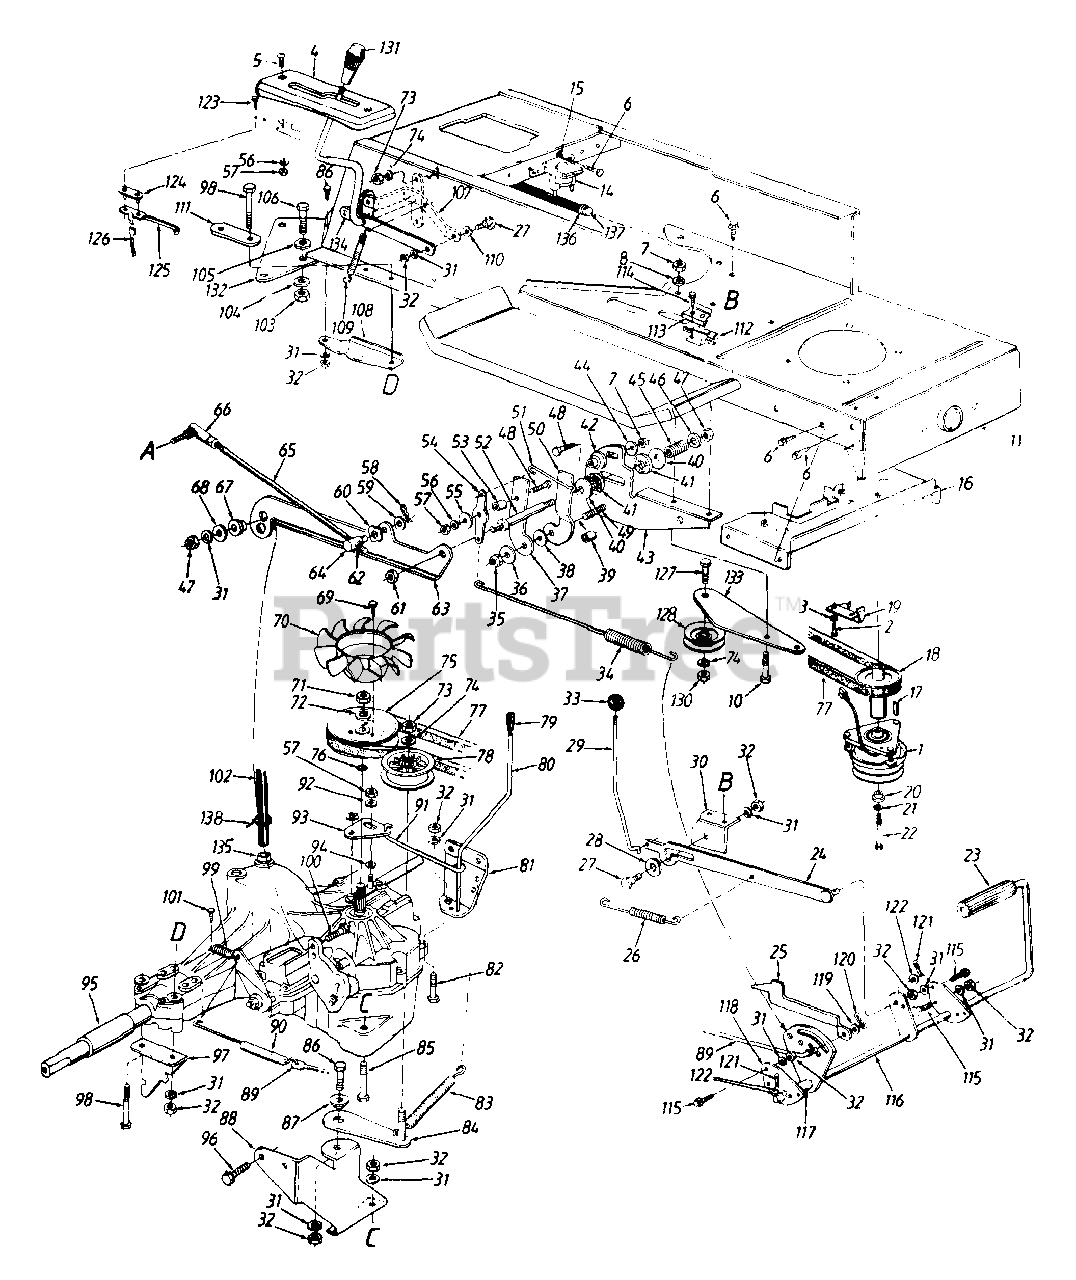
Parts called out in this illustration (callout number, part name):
1	Electric Clutch
2	Hex Bolt 5/16-18 x .75" Lg. (Gr. 5)
3	Bell-Wash. .345" I.D. x .88"
4	Index Bracket
5	Pan Hd. Mach. Scr. 1/4-20 x .75" Lg.
6	Hex Wash. Hd. TT-Tap Scr. 1/4-20 x .5" Lg.
7	Hex Nut 1/4-28 Thd.
8	L-Wash. 1/4" I.D.
10	Hex Bolt 1/4-28 x .75" Lg.
11	Lower Frame Ass'y.
14	Solenoid
15	Ext. L-Wash. 1/4" I.D.
16	Belt Guard Brkt. Ass'y.
17	Sq. Key 1/4" x 1.5" Lg.
18	Engine Pulley
21	L-Wash. 7/16" I.D.
22	Hex Bolt 7/16-20 x 3.25" Lg. (Gr. 5)
23	Foot Pad
26	Foot Pedal Return Spring
27	Shld. Bolt .437" Dia. x .268"
28	Fl-Wash. 7/16" I.D. x 1-3/8" O.D.
31	L-Wash. 5/16" I.D.
32	Hex Nut 5/16-18 Thd.
34	Neutral Return Spring
35	Hex Nut 5/16-24 Thd.
36	Fl-Wash. .344" I.D. x 1" O.D.
37	Scissor-Flat
38	Fl-Wash. .33" I.D. x 1.25" O.D.
40	Bell-Wash. .4" I.D. x 1.13" O.D.
41	Friction Washer
42	Centering Gauge Spacer
43	Neutral Return Mtg. Brkt.
44	Bell-Wash. .265" I.D. x .75" O.D.
45	Comp. Spring 1.19" Lg.
46	Fl-Wash. .312" I.D. x .75" O.D.
47	Hex Nut 5/16-24 Thd.
48	Hex Bolt 1/4-28 x 1" Lg. (Gr. 5)
49	Rib Neck Bolt 5/16-24 x .84" Lg.
50	Scissor-Offset
51	Neutral Return Rod
52	Friction Disc Stud
53	Shld. Spacer
54	Neutral Return Lever
55	Fl-Wash. .265" I.D. x 1" O.D.
56	L-Wash. 1/4" I.D.
57	Hex Nut 1/4-20 Thd.
58	Hairpin Clip
59	Fl-Wash. .375" I.D. x .87" O.D.
60	Spring Wash. .39" I.D.
61	Hex L-Nut 3/8-24 Thd.
62	Hex Jam Nut 3/8-24 Thd.
63	Neutral Return Brkt.
64	Ferrule 3/8-24 Thd.
65	Control Rod
66	Ball Joint 3/8-24 Thd.
67	Shld. Spacer .5" Dia. x .27" Lg.
68	Fl-Wash. .349" I.D. x .879" O.D.
69	Hex Wash. Hd. Tap Scr. #12 x 3/8" Lg.
70	Fan
71	Hex Nut 1/2-20 Thd.
72	L-Wash. 1/2" I.D.
73	Hex Nut 3/8-24 Thd.
74	L-Wash. 3/8" I.D.
75	Transmission Pulley
76	Wire Ring
77	"V"-Belt
78	Fl-idler Pulley 2.75" O.D.
79	Rod End Grip
80	Bypass Control Lever
83	Ext. Spring 6.12
86	Hex Bolt 5/16-18 x .75" Lg.
87	Shld. Spacer .5" Dia. x .27" Lg.
90	Ext. Spring
91	Bypass Actuator Rod
92	Fl-Wash. .281" I.D. x .5" O.D.
93	Bypass Adjustment Brkt.
94	External L-Wash. 1/4" I.D.
95	Sleeve .758" I.D. x 1" O.D.
96	Hex . Wash. TT-Tap Scr. 5/16-18 x .62" Lg.
99	Tension Spring
100	Hex Bolt 5/16-24 x 1" Lg. (Special)
101	Hex Wash. Hd. AB-Tap Scr. #10 x .5" Lg.
102	Hose 20" Lg.
103	Hex Nut 7/16-14 Thd. (Gr. 5)
104	Fl-Wash. .469" I.D. x .875" O.D.
105	Bell-Wash. .46" I.D. x 1.13" O.D.
106	Hex Bolt 7/16-14 x 1" Lg.
107	Speed Control Lever Ass'y.
110	Spr-Wash. .445" I.D. x .75" O.D.
112	Safety Switch (Clutch)
113	Switch Plate
114	Truss Mach. B-Tap Scr. #10 x .5" Lg.
115	Hex Wash. TT-Tap Scr. 5/16-18 x .75" Lg.
120	Cotter Pin 3/32" Dia.
121	Cotter Pin 1/8" Dia.
122	Fl-Wash. .64" I.D. x .94" O.D.
123	Hex Wash. Hd. AB-Tap Scr. #8 x .5" Lg.
124	Insulator Nut Plate
125	Reverse Safety Switch
126	Extension Wire
127	Hex Bolt 3/8-16 x 1.5" Lg.
128	Idler Pulley
130	Hex Nut 3/8-16 Thd.
132	Hitch Plate Extension
135	Hose Fitting
136	Plastic Vent
137	Plastic Vent Cap
